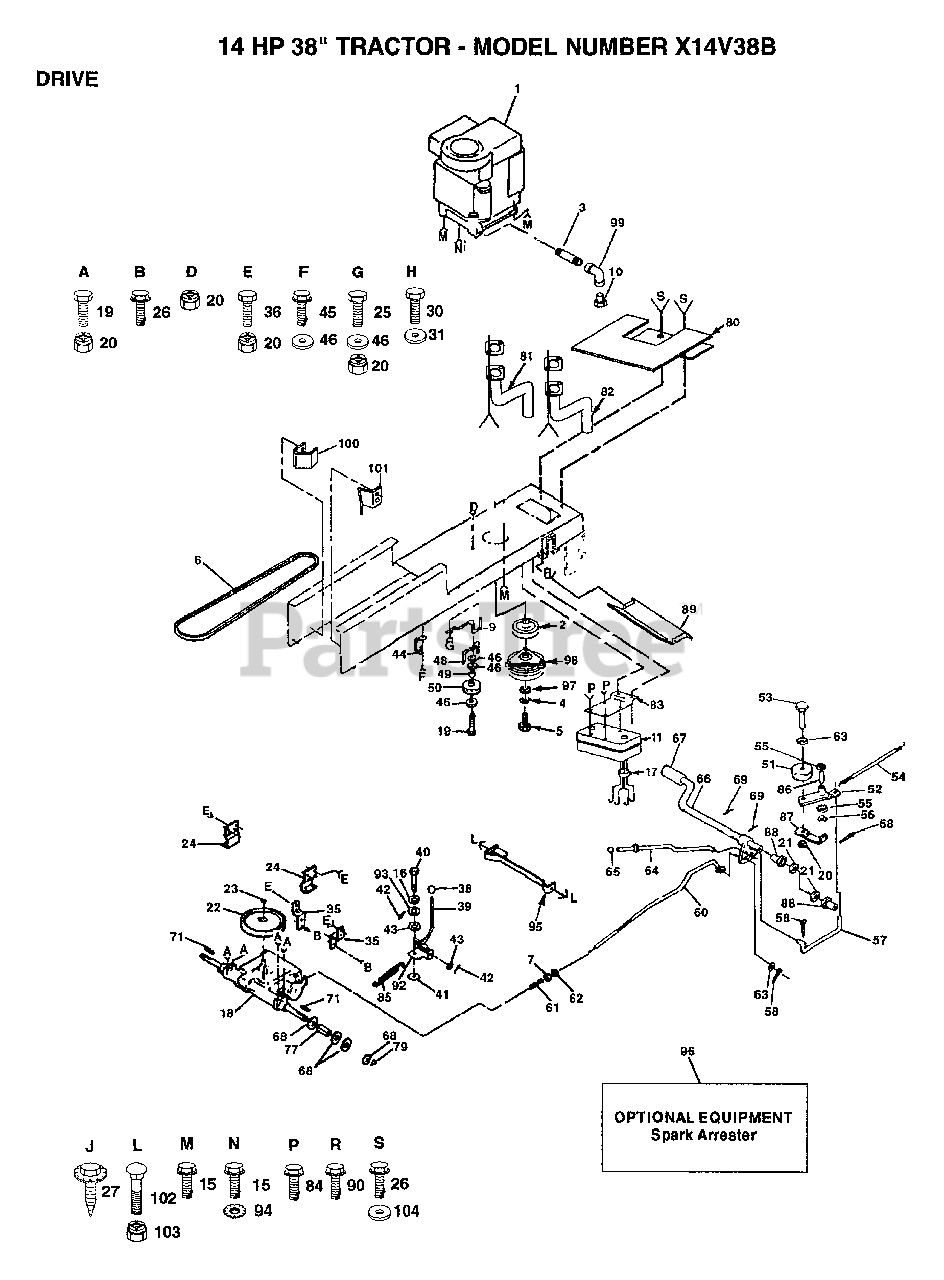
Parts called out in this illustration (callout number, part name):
3	PIPE NIPPLE LT
4	LOCKWASHER
6	BELT-V.90.0.GD.DR
6	PLUNGER CAP T
7	NUT
9	KEEPER.BELT.ENG.L
15	SCREW LT
16	LOCKWASHER
17	DEFLECTOR.222573
19	BOLT
21	WASHER LT
22	PULLEY TRANS
24	BRACKET LT
25	BOLT
26	SCREW
30	"BOLT,HEX"
31	WASHER T
35	STRAP TORQUE
38	KNOB T (1/2-HOLE)
39	ROD SHIFTER
42	WASH-SHFT PLT LT
42	PIN COTTER 1/8
43	WASHER
45	SCREW
46	WASHER
48	BELT KEEPER LT
49	SPACER T
50	PULLEY.IDLER.FLAT
52	ARM IDLER
54	"SPRING, RETURN LT"
55	WASHER LT
56	KLIP RING
57	"LINK, CLUTCH T"
58	COTTER PIN
61	SPRING ROD LT
62	NUT
63	WASHER
64	PARKING BRAKE ROD
67	PEDAL COVER T
68	WASHER
71	SQUARE KEY
77	SPACER LT
79	E-RING LT
81	TUBE ASSY EXH LH
82	TUBE ASSY EXH RH
83	BRACKET MUFFLER
84	SCREW ST
86	"LY, BEARING"
87	RETAIN BELT
88	NYLON BEARING
89	HEAT SHIELD
90	SCREW
92	PLATE SHIFT LT
93	WASHER LT
94	LOCKWASHER
97	WASHER
99	ELBOW
100	"KEEPER,BELT LH T"
101	"KEEPER,BELT RH T"
102	BOLT
104	WASHER
